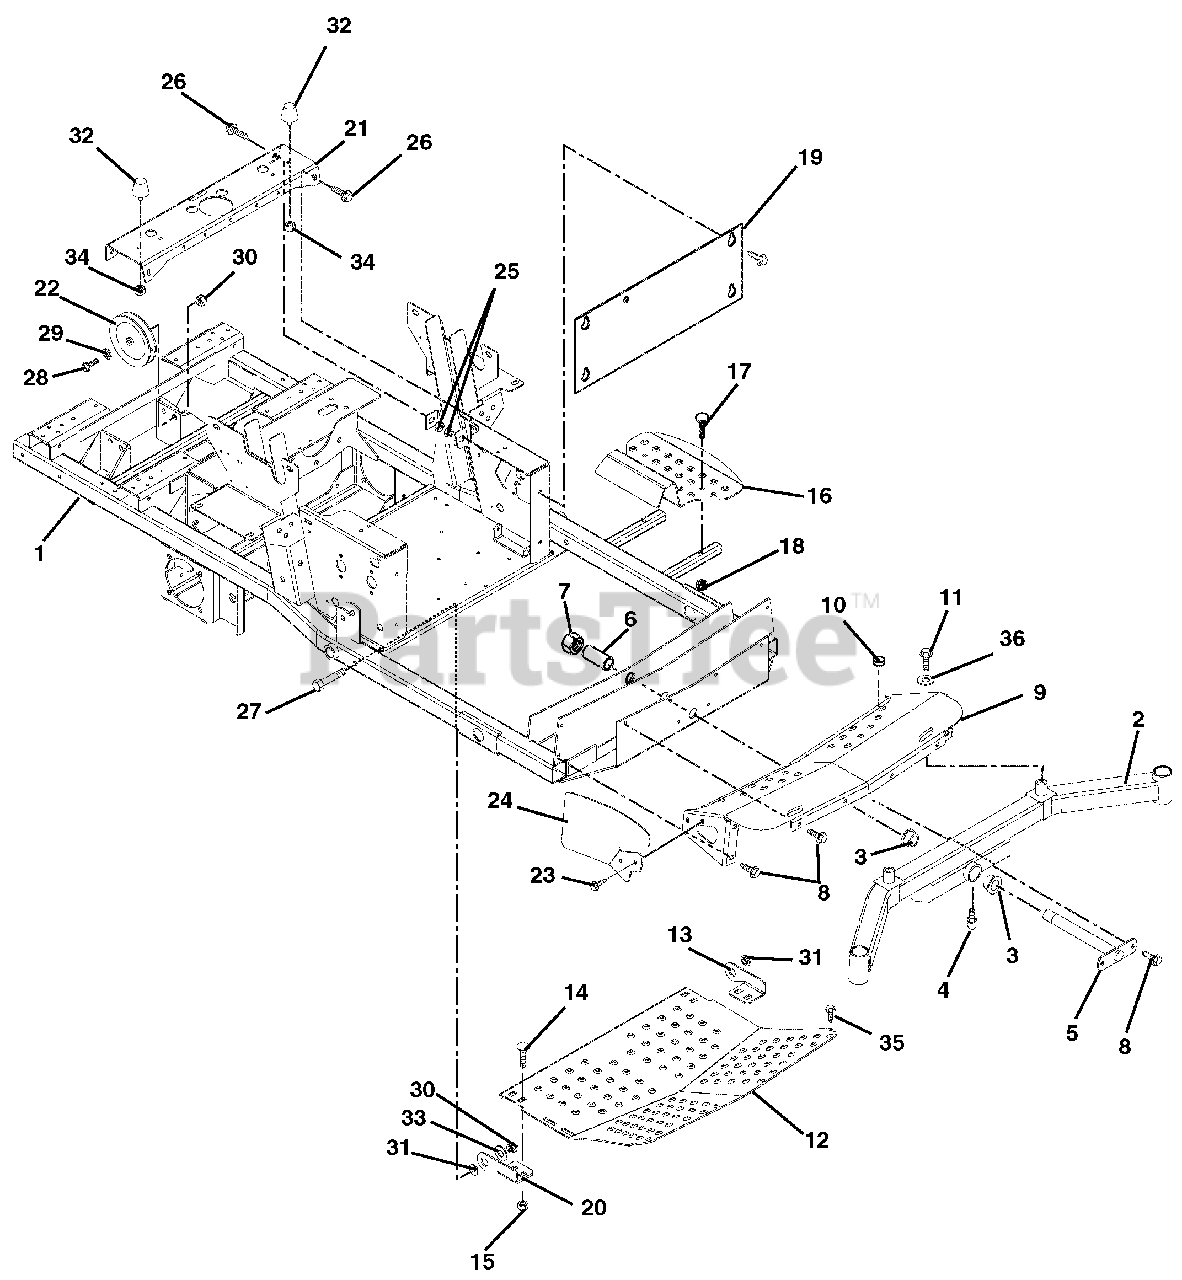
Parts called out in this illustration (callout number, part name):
1	Weldment, Frame
2	Weldment, Front Axle
3	Bushing, Flange 1.020 x 1.385 x .75 x 1.75
4	Fitting, Lube .25-28 x .256
5	Pin, Axle
7	Nut, Locking Nylon 1.0-14
8	Screw, Tapping .38-16 x .75
9	Weldment, Axle Cover
10	Button, Bumper
11	Bolt, Hex .50-20 x 1.00 Grade 5
12	Panel, Inspection
13	Hinge, Footboard Left Hand
14	Bolt, Round Head Square Neck .38-16 x 1.00 Grade 5
15	Nut, Locking Top Flange .38-16
16	Step, Ingress
17	Bolt, Round Head Square Neck .31-18 x 1.75 Grade 5
18	Nut, Locking Top Flange .31-18
19	Plate, Kick
20	Hinge, Footboard Right Hand
21	Channel, Cross
22	Pulley, Idler
23	Screw, Tapping .25-20 x .50 Hex Washer Head
24	Guard, Foot
25	Nut, Retainer .375-16 x .37
26	Bolt, Serrated Flange Washer Head .38-16 x 1.00
27	Bolt, Hex .50-13 x 3.25 Grade 5
28	Bolt, Hex .50-13 x 2.25 Grade 5
29	Washer, Flat Steel .505 x .88 x .072
30	Nut, Locking Top Flange .50-13
31	Bushing, Flange .515 x .75 x .275 x 1.12
33	Washer, Flat Steel .563 x 1.38 x .109
34	Nut, Locking Flange .312-24
35	Screw, Tapping Hex Washer Head .38-16 x 1.00
36	Washer, Flat Steel .518 x 2.00 x .105
